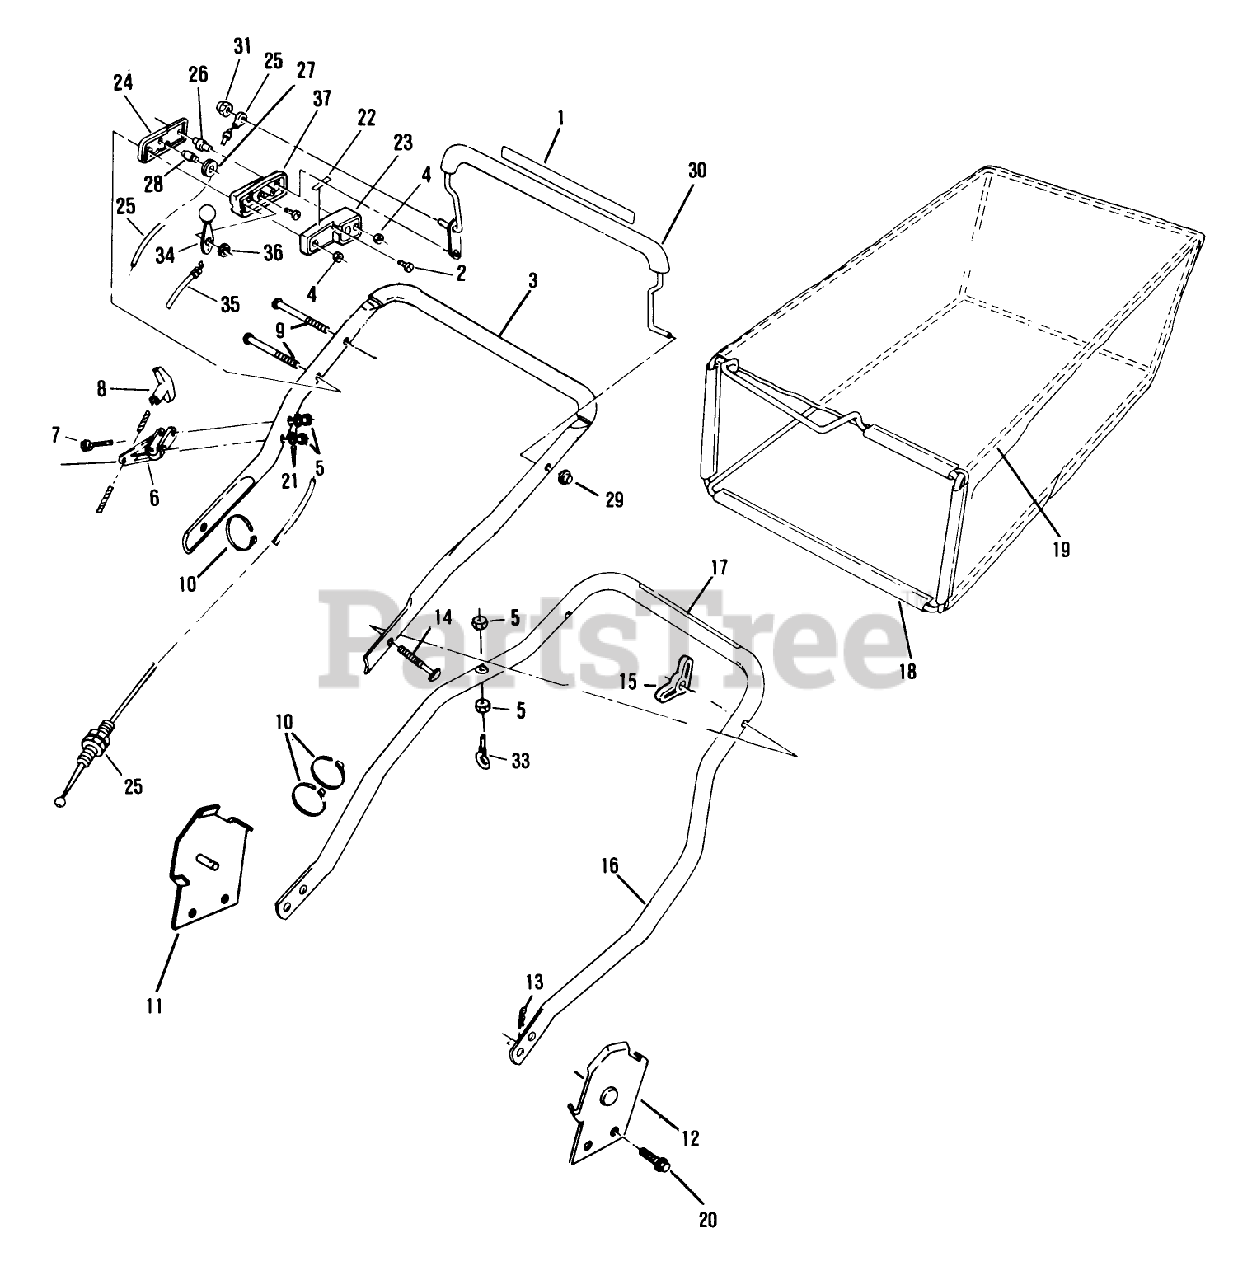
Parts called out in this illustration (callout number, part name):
2	SCREW
3	HANDLE-TOP *G
4	NUT C/LOCK E
5	LOCKNUT E
8	HANDLE START UM&D
9	SCREW
13	HAIR PIN
14	BOLT QUALITY
15	NUT-WING
21	WASHER
25	CONTROL CABLE WES
26	COLUMN
27	PULLEY PL
28	PIN SKF
31	NUT ACORN
33	EYE BOLT WAS MFG
34	LEVER&KNOB AY WES
35	CABLE THROT WES
36	WASHER-SPRING
